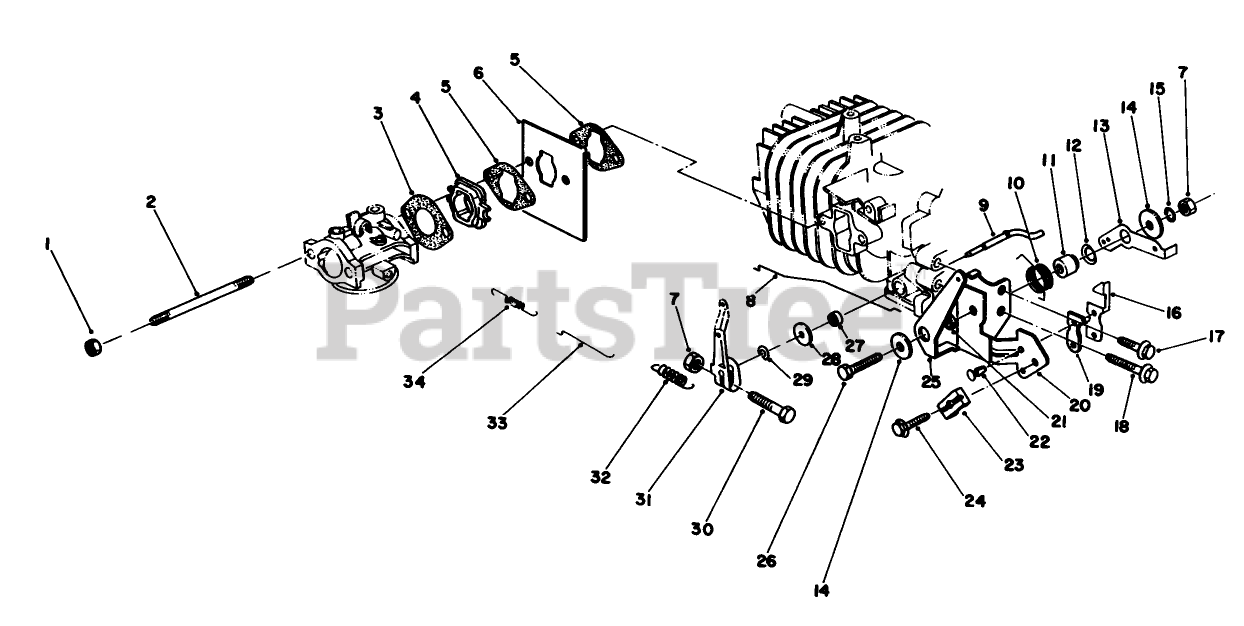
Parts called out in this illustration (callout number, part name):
2	CARB STUD BOLT
3	GASKET-CARB
4	INSULATOR
5	GASKET-CARBURETOR
9	Shaft-Governor
15	LOCKWASHER
16	TERMINAL-KILL SWITCH
19	INSULATOR-KILL SWITCH
23	CLAMP-CABLE
27	SEAL-OIL
28	WASHER
33	ROD-CARBURETOR
34	SPRING
